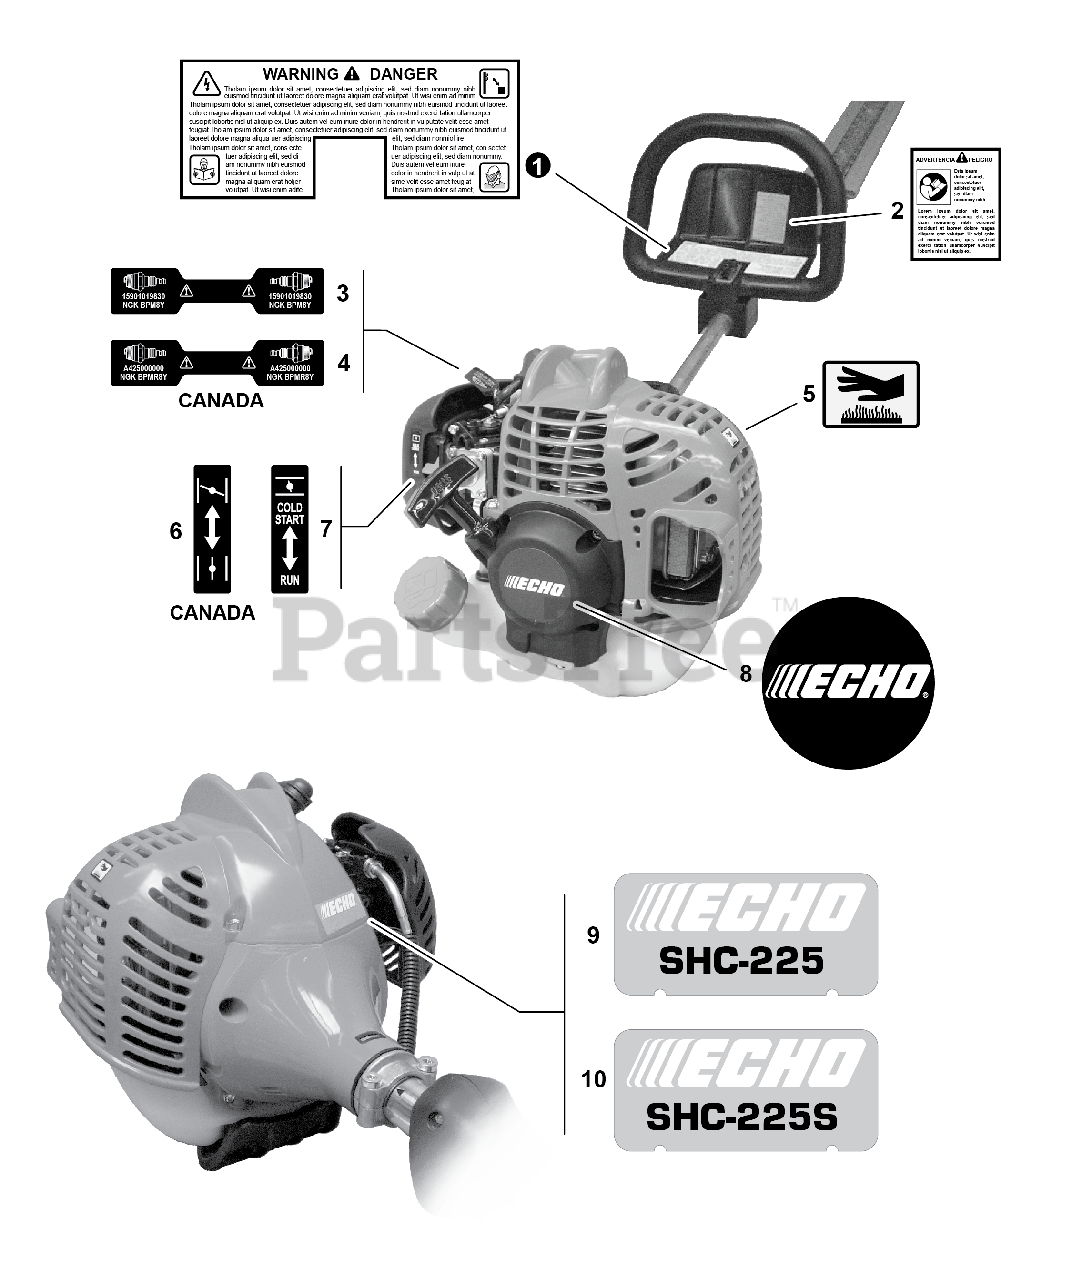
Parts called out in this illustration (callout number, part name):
1	LABEL - WARNING
2	LABEL - CAUTION -- SPANISH
3	LABEL - SPARK PLUG -- BPM8Y
4	LABEL - SPARK PLUG -- BPMR8Y
5	LABEL - HOT SURFACE
6	LABEL - CHOKE
7	LABEL - CHOKE
8	LABEL - ECHO
9	LABEL - MODEL -- SHC-225
10	LABEL - MODEL -- SHC-225S
